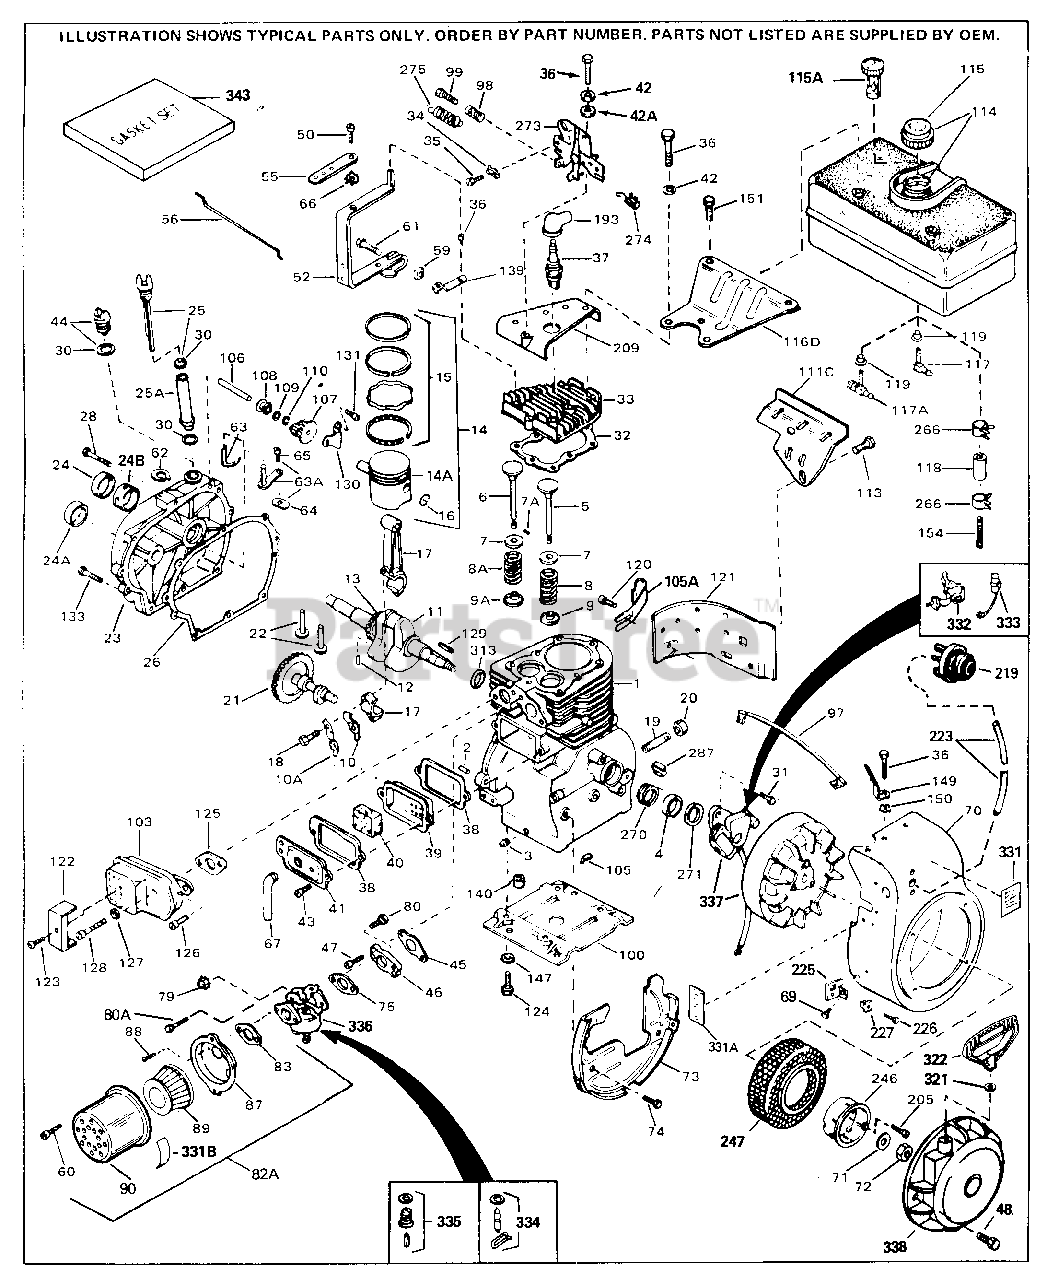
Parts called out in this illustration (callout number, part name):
1	"Cylinder (Incl. 2, 3, 4 & 76) 2-3/4" Bore
2	Dowel Pin
3	Oil Drain Plug (Sq. hd., 1/4-18)
4	Seal, Oil
5	Intake Valve (Std.) (Incl. 9)
5	Intake Valve (1/32" OS) (Incl. 9)
6	Exhaust Valve (Std.)(Incl. 151)
6	Exhaust Valve (1/32" OS) (Incl. 151)
7	Valve Spring Cap
7A	Pin, Valve spring retainer Use as req uired
8	Valve Spring
8A	Valve Spring
9	Cap, Lower valve spring
9A	Cap, Lower valve spring
10	Dipper, Oil
10A	Plate, Lock & Oil dipper This plate m ay be replaced by 34242 oil dipper bu t 650662C screw must be used.
11	Crankshaft
12	Pin, Crankshaft gear
13	Gear, Crankshaft (Used in early produ ction) This gear is servicable only when it is pinned to the crankshaft.
14	Piston, Pin & Ring Set (Std.) 2-3/4" Bore
14	Piston, Pin & Ring Set (.010" OS)
14	Piston, Pin & Ring Set (.020" OS)
14A	Piston & Pin Ass'y. (Std.)(2-3/4") In cl. 16
14A	Piston & Pin Ass'y. (.010" OS) Incl. 16
14A	Piston & Pin Ass'y. (.020" OS) Incl. 16
15	Ring Set (Std.) (2-3/4" Bore)
15	Ring Set (.010" OS)
15	Ring Set (.020" OS)
16	Piston Pin Retaining Ring
17	Rod Assy., Connecting (Incl. 10 & 18)
18	Screw, Connecting rod (2 each)
21	Camshaft (MCR)
22	Lifter, Valve
23	Cover, Cylinder (Incl. 24, 106 & 279)
24	Oil Seal
24B	Bushing, Crankshaft (Use as required)
25	Dipstick, Oil (Incl. 30)
26	* Gasket, Cylinder cover
28	Screw, 1/4-20 x 1-1/4"
30	* Gasket, Oil filler
31	Screw, 10-24 x 1"
32	* Gasket, Cylinder head
33	Head, Cylinder
34	Conduit Clip
35	Screw, 10-32 x 3/8"
36	Screw, 5/16-18 x 2" (Use as required)
36	Screw, 5/16-18 x 2-1/4" Use as requir ed
36	Screw, 5/16-18 x 2-1/2" Use as requir ed
37	Resistor Spark Plug - RJ17LM
37	Resistor Spark Plug
38	* Gasket, Breather cover
39	Breather Body
40	Breather Element
41	Valve Cover
42	Washer, Flat (Use as required)
42A	Washer, Belleville (Use as required)
43	Screw, 10-24 x 1/2"
45	* Gasket, Intake
46	Flange Carburetor
47	Screw, 5/16-18 x 3/4"
48	Screw, 1/4-28 x 7/16"
50	Screw, 8-32 x 5/16"
52	Lever Assy., Governor
56	Link, Throttle
59	Lock Nut, 10-32
60	Screw, 8-32 x 3/8"
61	Screw, 10-32 x 3/4"
62	Retaining Ring
63	Governor Rod Ass'y. This one-piece go vernor rod is no longer used. It is r eplaced by 30699C ass'y.,Ref. no. 63A
63A	Rod Assy., Governor (Incl. 64 & 65)
64	Yoke, Governor
65	Screw, 6-40 x 5/16"
66	Lock Washer #8
69	Screw, T-40, 5/16-24 x 21/32"
70	Blower Housing (For elec.star.) Incl. 134,135
71	Washer, Belleville
72	Nut, Hex
73	Blower Housing Baffle (without electr ic starter knock-out) (Use as require d)
73	Blower Housing Baffle (with electric starter knock-out) (Use as required) (Point Ignition)
74	Screw, 1/4-20 x 5/8"
75	* Gasket, Carburetor
80A	Screw, 1/4-20 x 27/32"
82A	Air Cleaner Ass'y. (Incl. 60, 83, 87, 88, 89, 90A & 331B) (Use as required )
83	* Gasket, Air cleaner
87	Bracket, Air cleaner NOTE: 130010 thr u 10C & 11 used in early production o nly.
88	Screw, 10-32 x 1/2"
90	Body, Air cleaner
98	Spring, Compression
99	Screw, 5-40 x 7/16"
100	Base, Engine mounting
103	Muffler
106	Shaft, Mechanical governor
107	Gear Assy., Governor (Incl. 109)
108	Spool, Governor
109	Washer, Flat
110	Retaining Ring
111C	Bracket, Fuel tank
113	Screw, 1/4-20 x 5/8"
114	Fuel Tank (Incl. 292 & 301) (2 Quart)
115	Fuel Cap (Red 1-1/2" ID) (also availa ble in Packaged Part #740005B) (Char coal Plastic) (Spurt resistant, Low p rofile) (Use as required)
115	Fuel Cap (Red Plastic) (Spurt resista nt, High profile) (Use as required)
115	Fuel Cap (Red)
115	Fuel Cap (White Plastic)(Std) As requ ired
117A	Valve, Shut-off
118	Fuel Line (8.62") as req.)
118	Fuel Line (Braided 16") (41 cm) Use a s req.
118	Fuel Line (Braided 32") (81 cm) Use a s req.
120	Screw, 10-24 x 1/2" (Use as required)
121	Extension, Blower housing
122	Deflector, Exhaust
123	Screw, 1/4-15 x 7/8"
124	Screw, 5/16-18 x 3/4"
125	Gasket, Exhaust
126	Screw, 5/16-18 x 3/4"
128	Screw, 5/16-18 x 2" (Use as required)
129	Key, Flywheel
130	Bracket, Governor gear
131	Screw, 10-24 x 1/2"
133	Screw, 1/4-20 x 1-3/4"
149	Clip, Shorting
150	Lockwasher
151	Screw, 1/4-15 x 7/8"
193	Cover, Spark plug (Use as required)
205	Screw, 1/4-20 x 5/8" Use as required
209	Cover, Cylinder head
246	Cup, Starter
247	Starter Screen
266	Fuel Line Clamp
270	Bushing, Crankshaft (Use as required)
274	Terminal Ass'y. As req. on late produ ction
287	Wire Clip
287	Clip, Ground wire (Use as required)
331A	Decal, Instruction
332	Breaker Points (also available in Pac kaged Part #740037B)
334	Inlet Needle, Seat & Clip Assy.
336	Carburetor (Incl. 75) (Refer to Divis ion 5, Section A, page 100 for breakd own)
338	Rewind Starter Refer to Division 5, S ection C, page 25 for breakdown
343	Gasket Set (Incl. items marked*)
